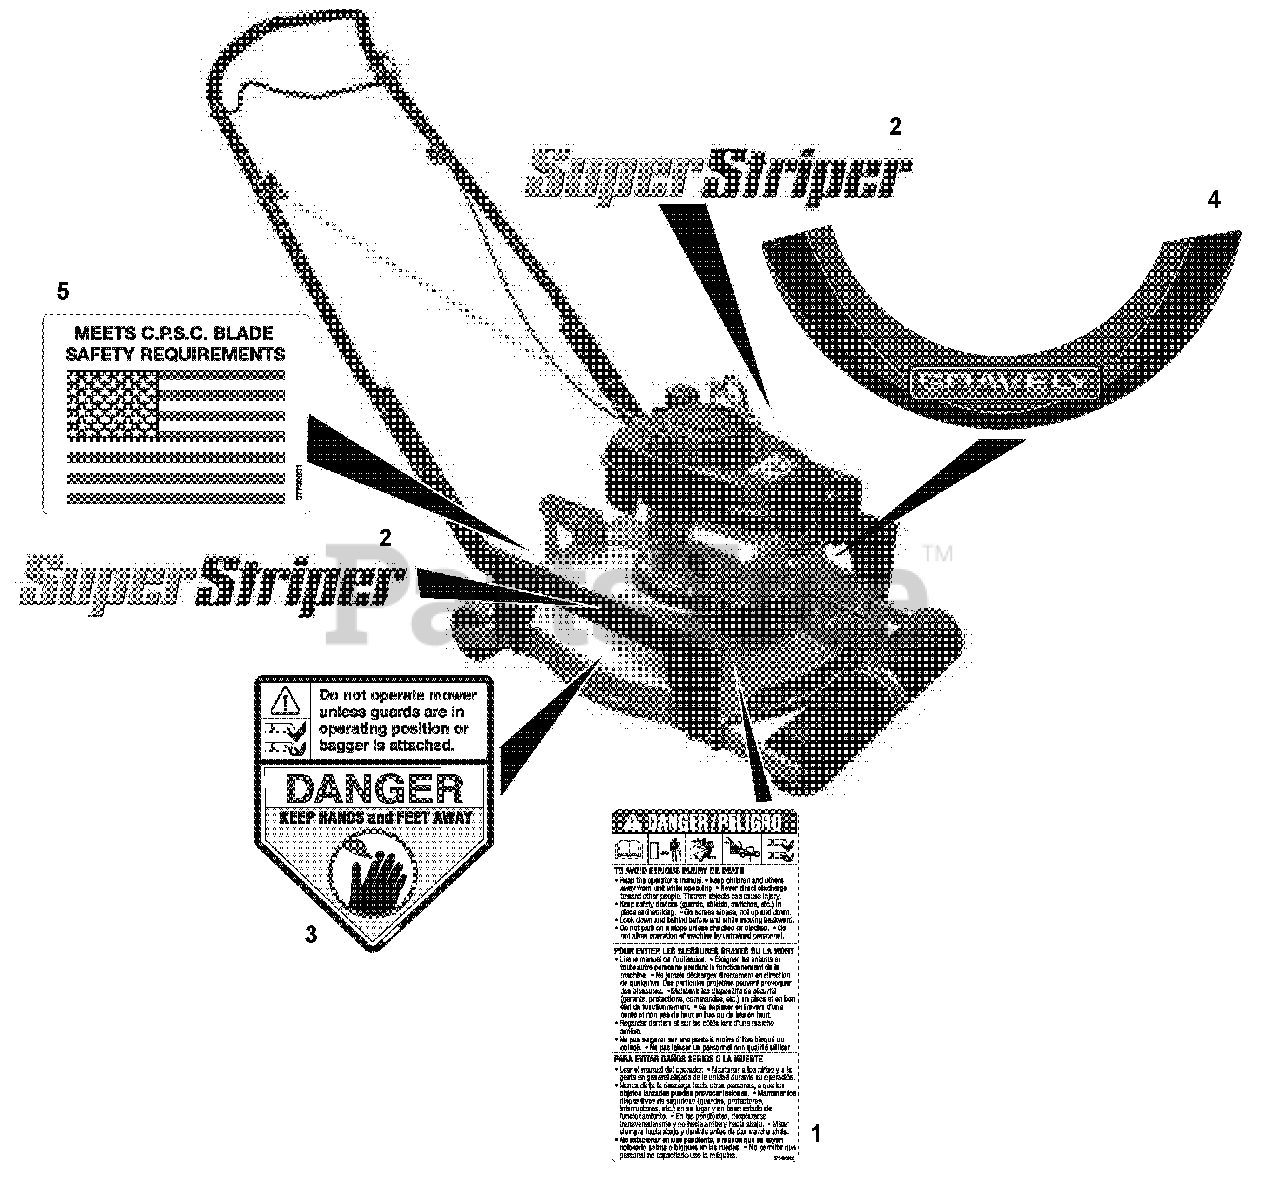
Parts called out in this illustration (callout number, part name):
1	Decal, Bilingual Danger
2	Decal, SuperStriper
3	Decal, CPSC Danger
4	Decal, SuperStriper Deck Top
5	Decal, CPSC USA Flag
